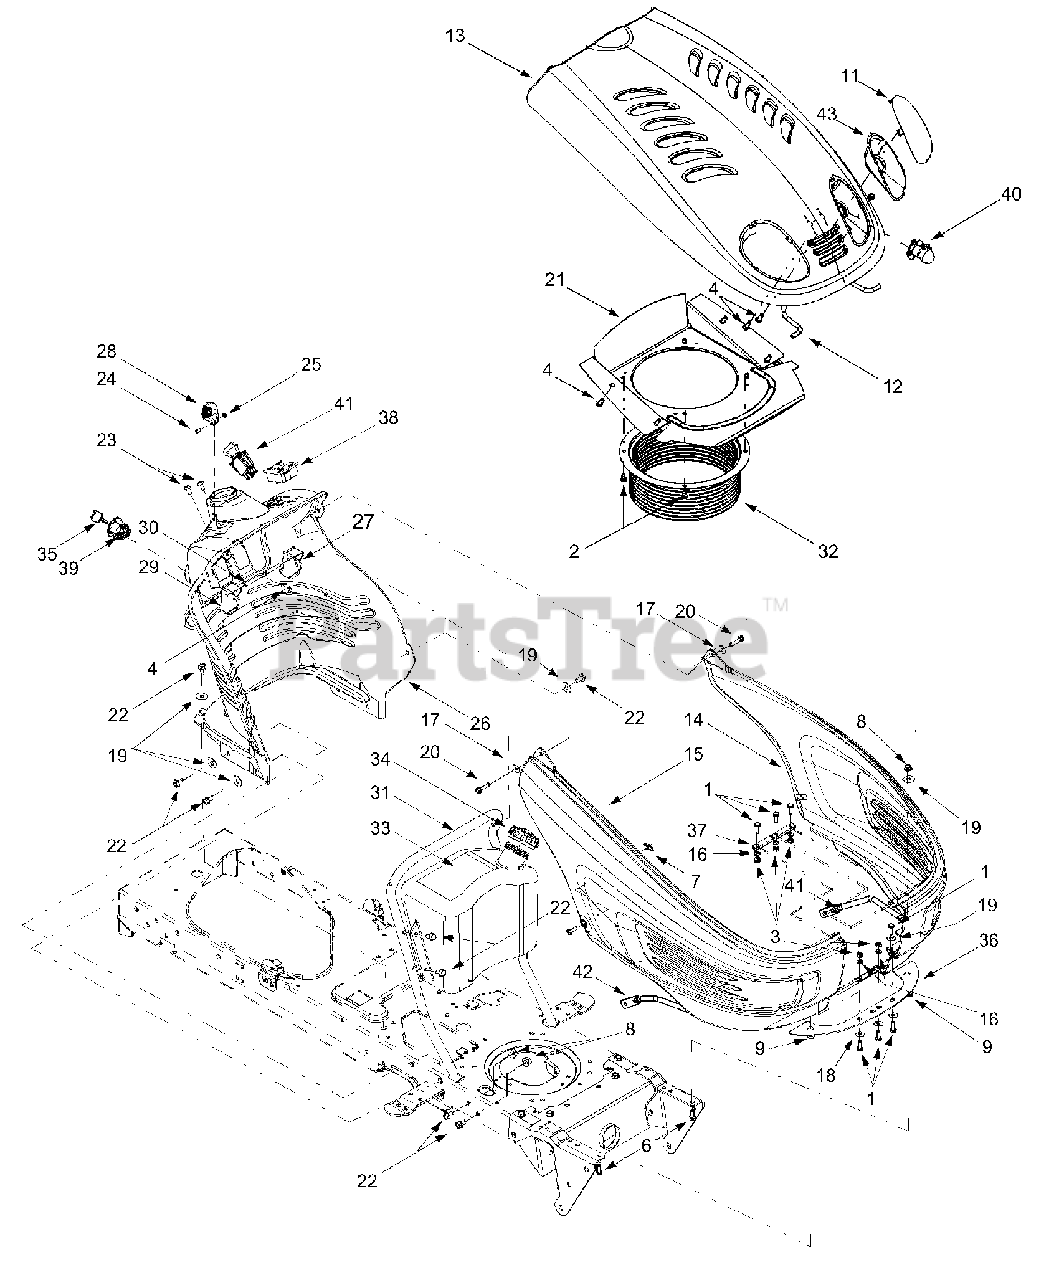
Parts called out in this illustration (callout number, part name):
1	Hex Cap Screw, 1/4-20 x .75
2	Self-tapping Screw, 1/4-20 x .5
3	Hex Nut, 1/4-20
4	Self-tapping Screw, 1/4-15 x .75
6	Hex Cap Screw, 5/16-18 x 1.25
7	U-type Speed Nut, 1/4-20
8	Flange Lock Nut, 5/16-18
9	Speed Nut
11	RH Head Light Lens
12	Hood Support Rod
13	Hood
14	LH Side Panel
15	RH Side Panel
16	Lock Washer, 1/4
17	Flat Washer, .283 x .75 x .030
18	Flat Washer, .28 x .74 x .063
19	Flat Washer, .349 x 1.0 x .063
20	Self-tapping Screw, 1/4-20 x 1.25
22	Self-tapping Screw, 5/16-18 x .625
23	Torx Self-tapping Screw, 1/4-14 x .625
24	Torx Screw, #8-32 x .375
25	Hex Nut, 8-32
26	Dash Panel, 4-style
27	Parking Brake Button
28	Throttle Control Lever
29	Cruise Control Button
30	Brake/Cruise Pivot Rod
33	Fuel Tank, 2-gallon
34	Fuel Cap
35	Ignition Key w/ plastic cover
36	Heat Shield
39	Ignition Switch
40	Headlight Assembly
